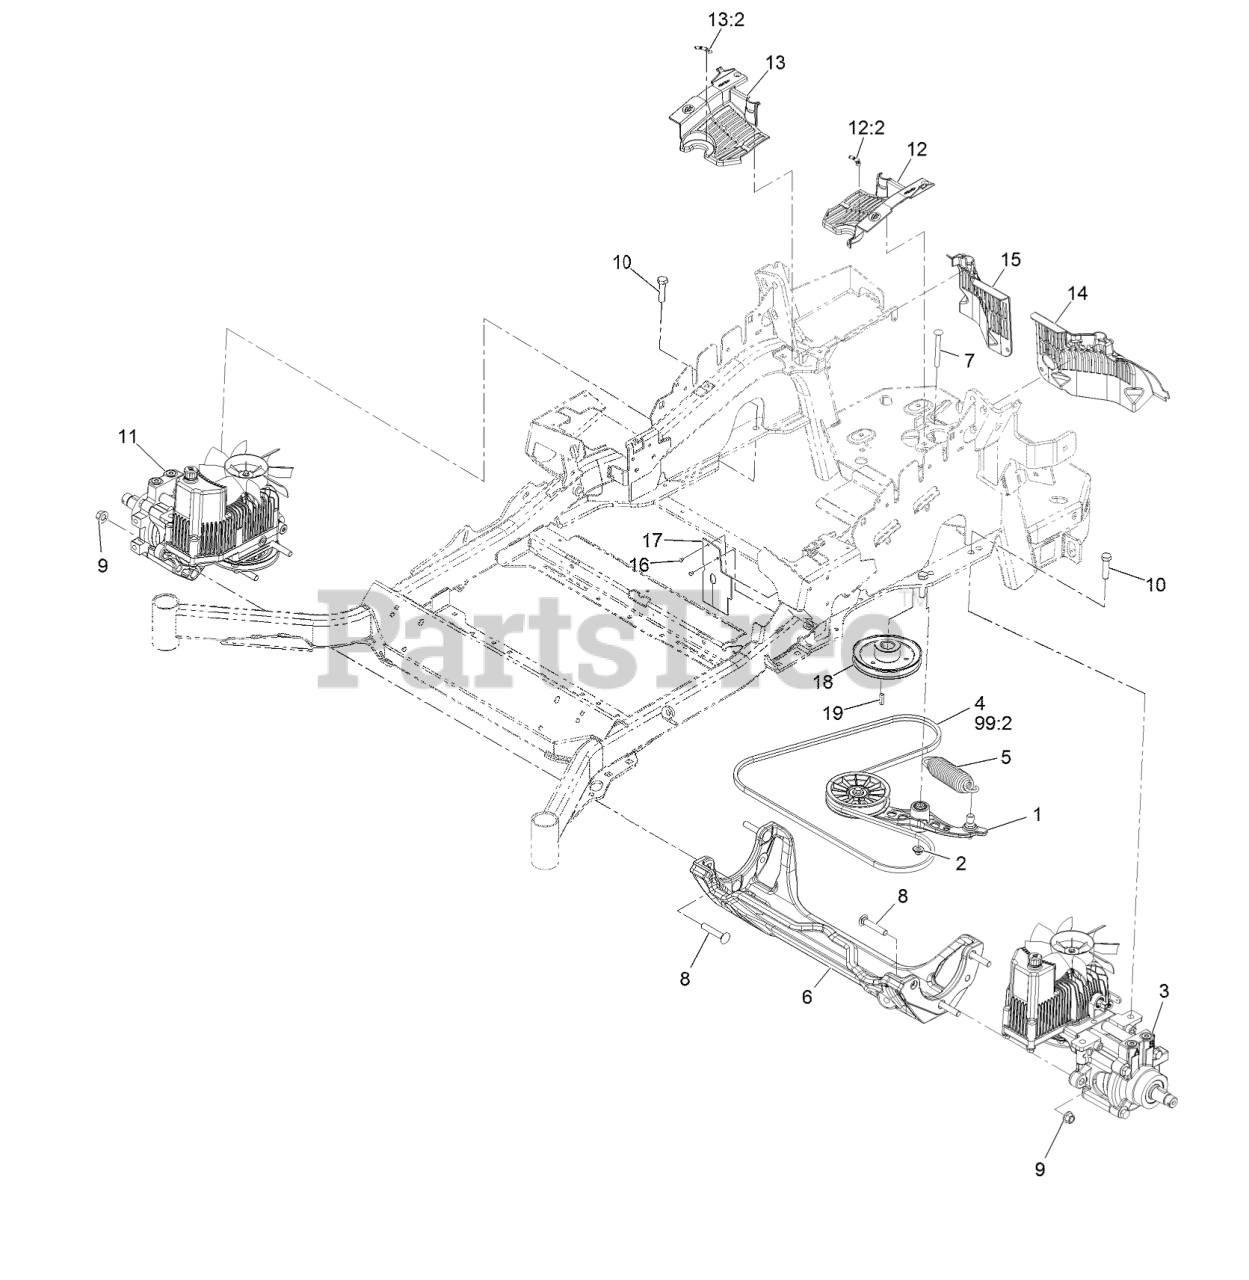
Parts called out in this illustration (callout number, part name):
1	PUMP IDLER ASM
2	Nut-Nyloc 3/8-16 Flg
3	LH HYDRO ASM (16CC W/ SHO
4	BELT
5	SPRING-EXTENSION
6	CRADLE-HYDRO
7	BOLT-SHOULDER, CARRIAGE 3/8-16 X 3 1/2
8	SCREW-CARR
9	Nut-Lock 1/2-13
10	SCREW-HH
11	RH HYDRO ASM (16CC W/ SHO
99:2	BELT
